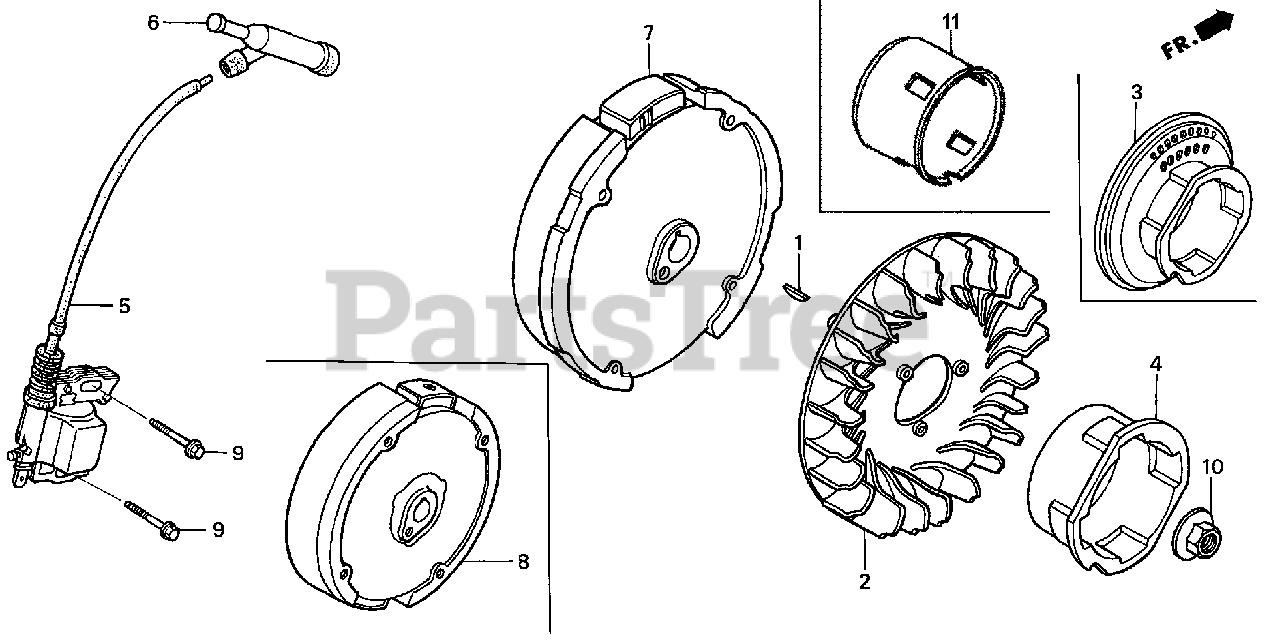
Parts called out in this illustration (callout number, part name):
1	KEY, SPECIAL WOODRUFF (25X18)
2	FAN, COOLING
3	PULLEY, STARTER
5	COIL ASSY., IGNITION
6	CAP ASSY., NOISE SUPPRESSOR (NICHIWA Y-EZ RTFM256)
7	FLYWHEEL
9	BOLT, FLANGE (6X25) (CT200)
10	NUT, SPECIAL (14MM)
